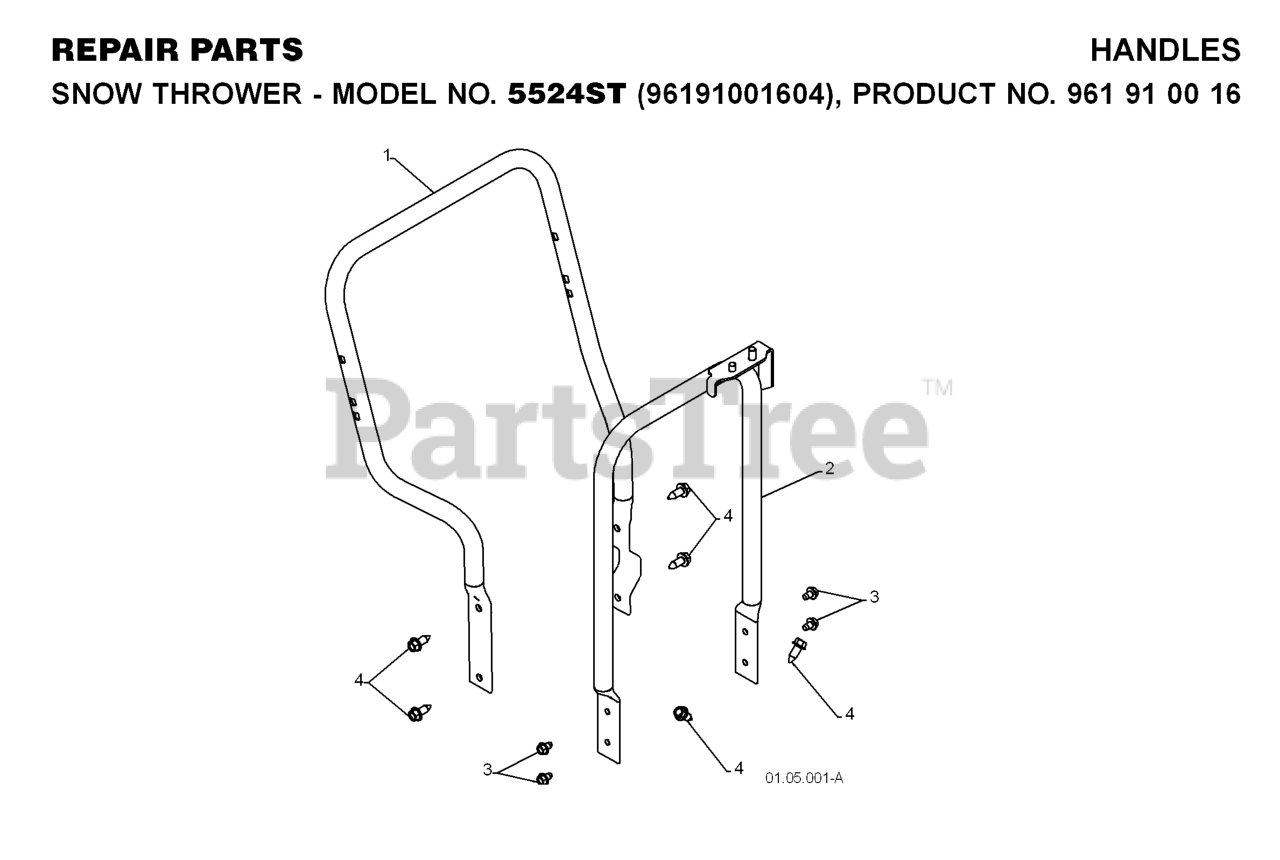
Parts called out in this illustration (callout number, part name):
1	TUBE.LOWER.HANDLE.SNOW.BLACK
2	SUPPORT.PIVOT.WELD
3	Screw 5/16-18 x 1/2 Hex, Self Tapping 5/16-18 x 1/2
4	SCREW 3/8-16X1
